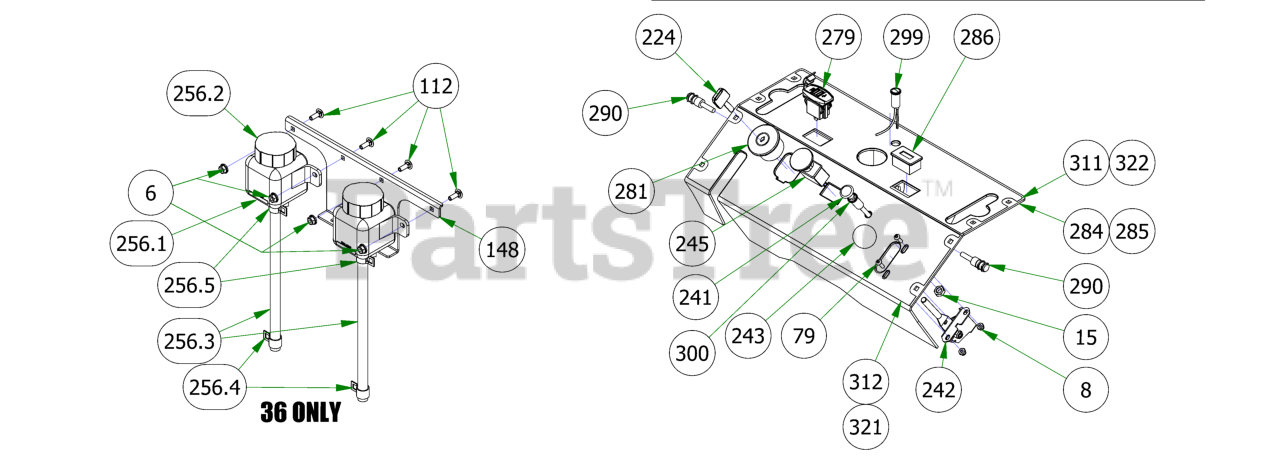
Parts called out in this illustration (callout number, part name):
2	8-32 HEX M/S NUT ZINC
6	1/4-20 NYL INSERT FLANGE LOCKNUT ZINC
8	10-24 NYLON INSERT LOCKNUT ZINC
11	3/8-16 NYLON INSERT FLANGE LOCKNUT (GR.F) ZINC
15	3/8-24 HEX NUT ZINC YELLOW
19	5/16-18 NYLON INSERT FLANGE LOCKNUT ZINC
23	5/16-18 HEX SERRATED FLANGE NUT HARD/ZINC
25	5/16-18 NYLON INSERT JAM LOCKNUT ZINC
45	M6-1.0 X 16MM DIN 933 HEX TAP BOLT (CL 8.8) ZINC
53	5/16-18 X 6 CARRIAGE BOLT (GR.5) ZINC
61	12-24 X 1/2 HEX WASHER UNLSOT F TCS ZINC
63	5/16-18 X 1-1/4 HEX C/S (GR.5) ZC
76	5/16-18 X 1-1/2 CARRIAGE BOLT ZINC
78	3/8-16 X 1-1/4 CARRIAGE BOLT ZINC
79	10-24 X 5/8 BUTTON SOCKET CAP SCREW 18-8 STAINLESS STEEL
90	3/8-16 X 1 GR 5 Hex Bolts Zinc
98	5/16-18 X 1 CARRIAGE BOLT (GR.8) ZINC
99	.390 ID X .750 OD X .062 THK FLAT WASHER NYLON
101	.390 ID X 1.12 OD X .125 THK FLAT WASHER NYLON
103	3/8 FLAT WASHER USS (1" OD) ZINC
104	3/8 SPLIT LOCKWASHER ZINC
112	1/4-20 X 3/4 CARRIAGE BOLT (GR.5) ZINC
125	1/4 DRIVE-TYPE STRAIGHT GREASE FITTING ZINC YELLOW)
131	ACS Spacer 3/4x3/8x1/4
147	Battery Hold Down Plate - Revolt
148	2020 36" Hydrotank Carrier Plate 2020 36" Stand On
165	Revolt Front Control Arm Stop Weldment BLACK
166	Revolt Rear Control Arm Stop Weldment BLACK
167	Revolt RH Drive Arm Actuator Weldment
168	Revolt LH Drive Arm Actuator Weldment
169	2019 Drive Arm Bushing
170	36" Revolt Rear Control Arm Stop Weldment 2020 36" BLACK
171	36" Front Control Arm Stop Weldment 2020 36" Stand On
172	36" RH Drive Arm Actuator Weldment 2020 36 REVOLT BLACK
173	36" Revolt LH Drive Arm Actuator Weldment 2020 36 BLACK
174	2019 Stand On Drive Arm Pivot Bar
176	2020 36 Stand On Drive Arm Pivot Bar
187	Brake Spring
192	2019 Revolt Push Rod Assembly
200	Console Bracket Weldment 2019 Stand On
204	36” Console Bracket Weldment 2020 Stand On
224	Ignition Key
234	1/4" Vinyl Tubing, 46" Long
235	3/16" Vinyl Tubing, 55" Long
242	Universal Throttle Head - 2012
243	Throttle Knob
245	PTO Switch
252	Brake Cable
254	Carbon Canister
256	Hydro Tank Assembly
256.1	350ml Expansion Tank
256.2	Hydraulic Tank Cap
256.3	ZT/Maverick Hydro Tank Hose
256.4	3/8" Hose Clamp
256.5	1/2 Hose Clamp
257	Interstate FAYTX14 Battery
258	8507A13 McMaster Carr Plunger
259	2019 Stand On Brake Handle BLACK
260	2019 Stand On Control Grip
262	Rubber Brake Grip-cZT/ZT 2013
272	2019 Stand On Waterbottle Cage
275	3/16 Vinyl Clamp
276	3/16" Vinyl Hose Clamp
278	Magnet-Steering Arm-Stand ON
280	Safety Switch
281	Ignition Switch
282	RH Podium Panel
283	LH Podium Panel
284	Podium Front Panel Weldment 2019 Stand On
285	36" Podium Front Panel Weldment 2020 Stand On
286	Tachometer
290	Safety Switch Harness
300	Code Indicator Light
311	2019 Revolt Control Panel Lower Decal
312	2019 Revolt Control Panel Upper Decal
321	36" Control Panel (upper) - Revolt
322	36" Control Panel (lower) - Revolt
